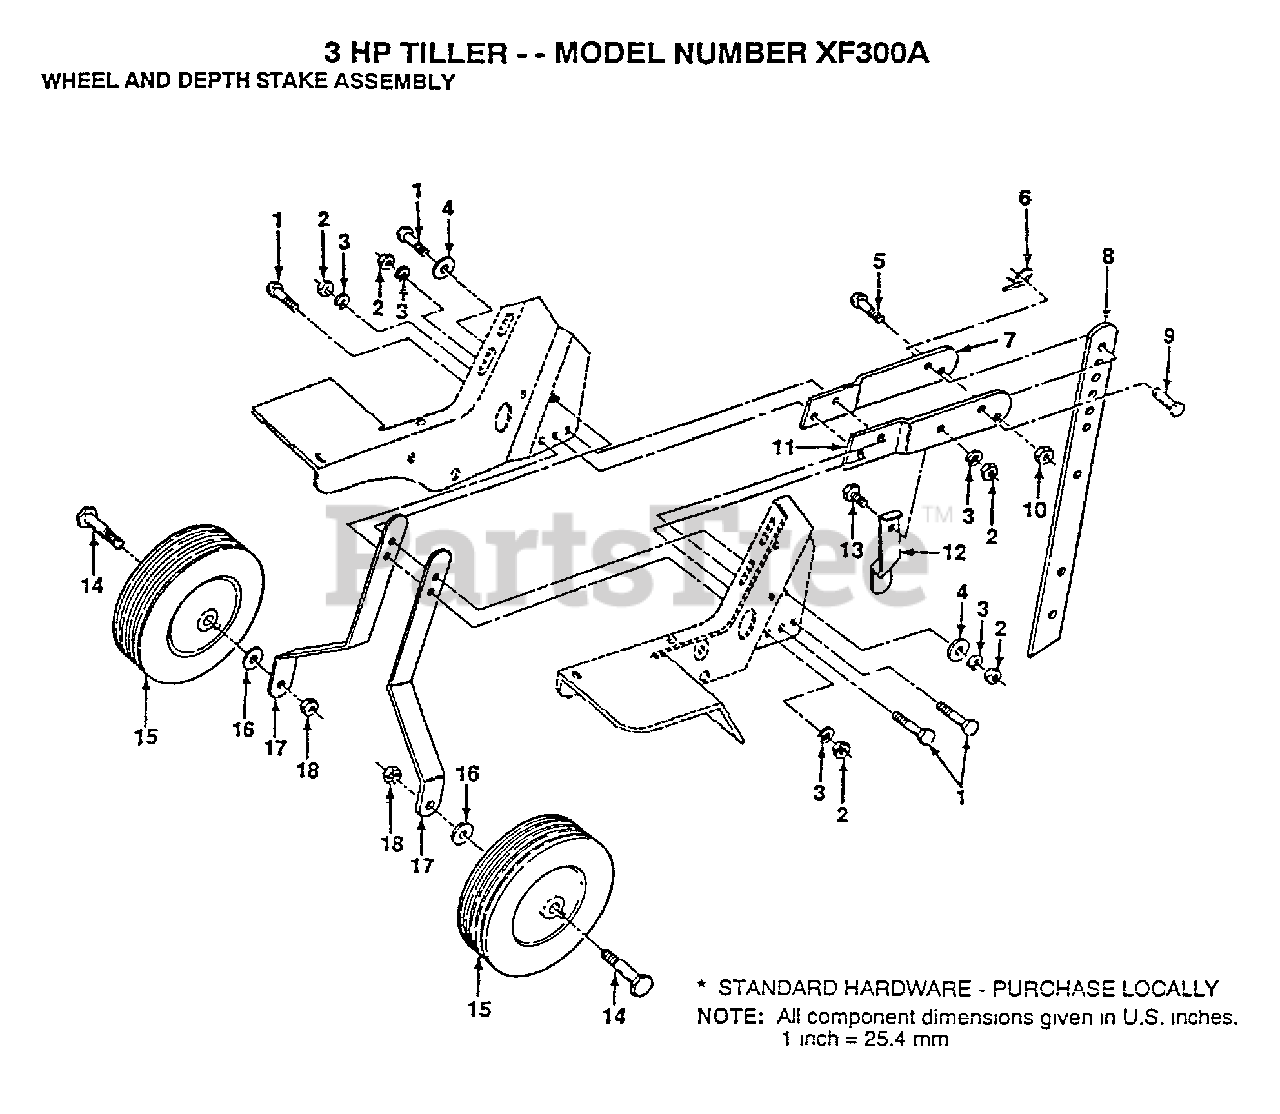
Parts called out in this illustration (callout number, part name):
2	NUT.HEX.5/16-18
3	LOCKWASHER
4	WASHER
5	BOLT.3/8-24X1-1/2
6	SPRING.RETAINER
7	STAKE.SUPT.TILLER
9	DRILLED RIVET RT
10	GRIPCO NUT
12	STAKE SPRING CT
13	BOLT
14	BOLT SHOULDER
16	WASHER
